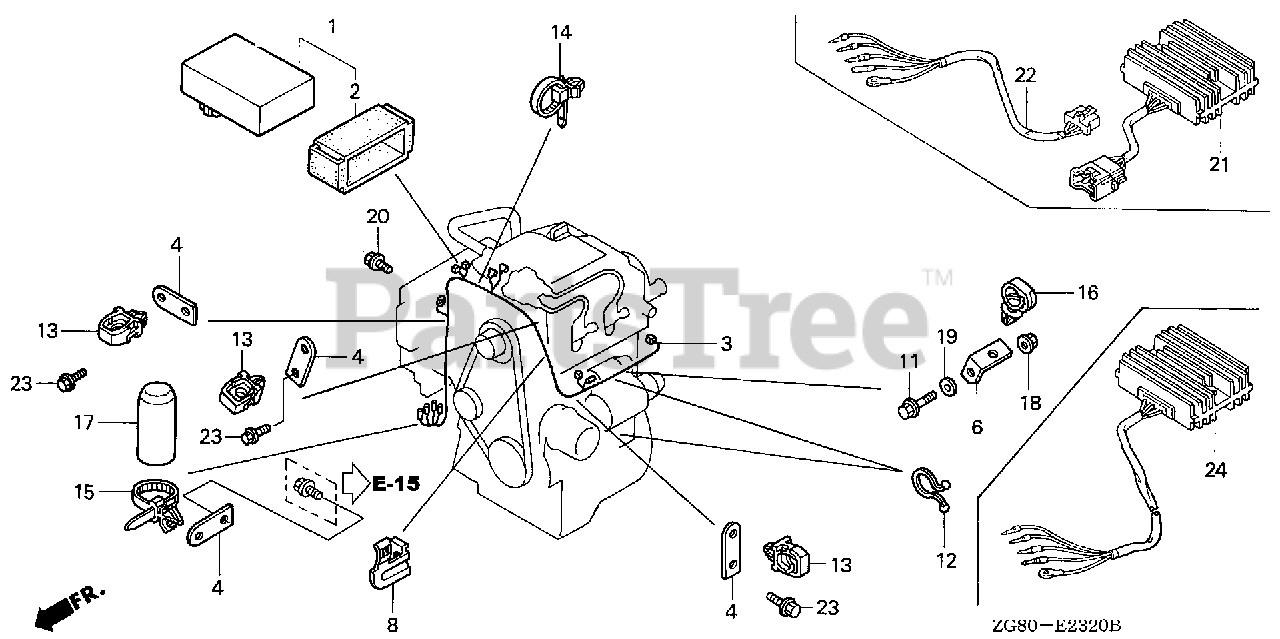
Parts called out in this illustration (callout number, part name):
1	MODULE, IGNITION CONTROL (CDI)
2	CUSHION, IGNITION CONTROL MODULE (CDI)
3	HARNESS ASSY., ENGINE
4	BRACKET, WIRE HARNESS CLIP
6	BRACKET, WIRE HARNESS CLIP (H)
8	STAY, SHEDDER VALVE CONNECTOR
11	BOLT, FLANGE (5X25)
12	CLIP, PURSE LOCK
13	CLIP, WIRE HARNESS (10MM)
14	STRAP, CABLE (105MM) (BLACK)
15	BAND, WIRE HARNESS (150MM) (BLUE)
16	CLIP, WIRE HARNESS (25MM)
17	TUBE, CORD (25MM)
18	NUT, FLANGE (5MM)
19	WASHER, PLAIN (5MM)
20	BOLT, FLANGE (6X12)
21	RECTIFIER ASSY., REGULATOR (20A)
22	SUB-WIRE HARNESS ASSY.
23	BOLT, FLANGE (6X14) (CT200)
